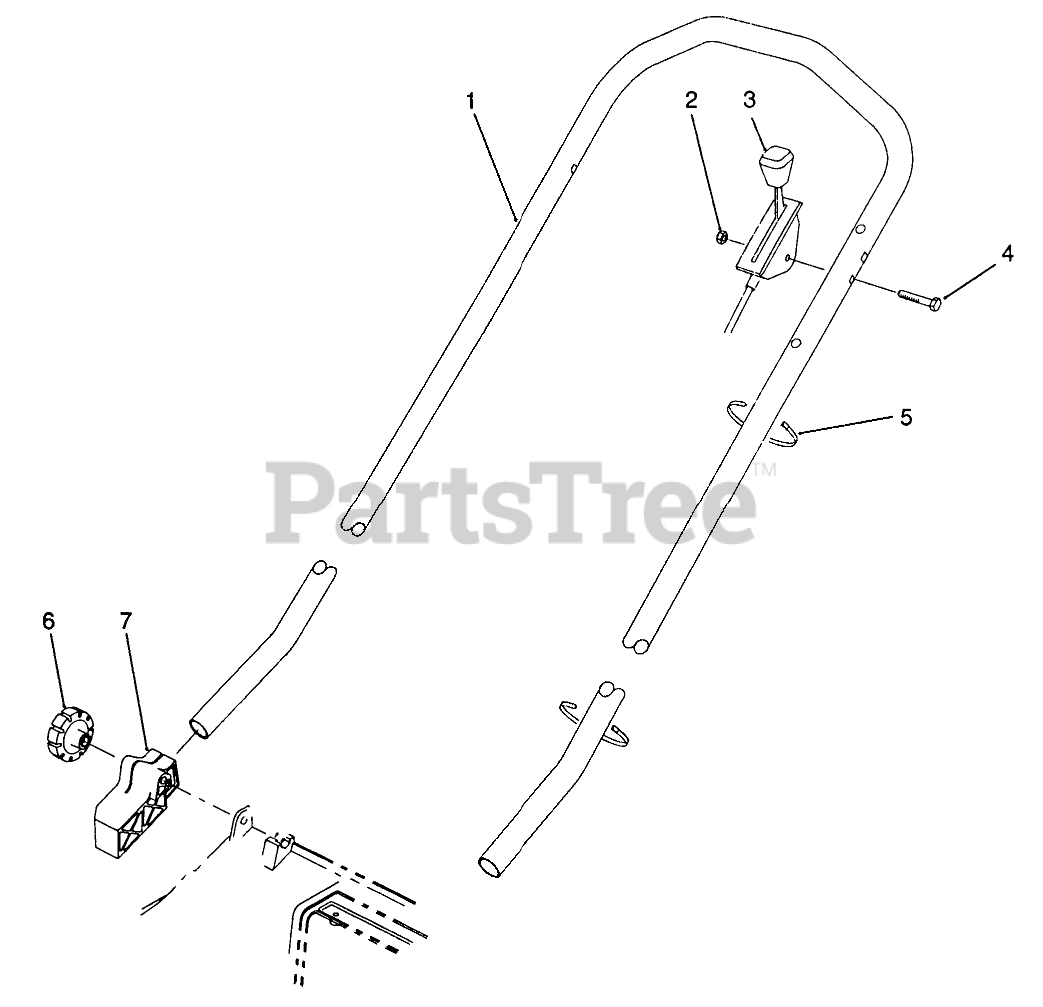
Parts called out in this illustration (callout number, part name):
1	Handle
2	NUT-LOCK, NI
3	Control-Throttle Bend Type #2 Sheath Lg. 44.00 Wire Lg. 2.50
4	SCREW-HANDLE
5	TIE-CABLE
7	MOUNT-HANDLE, LH
